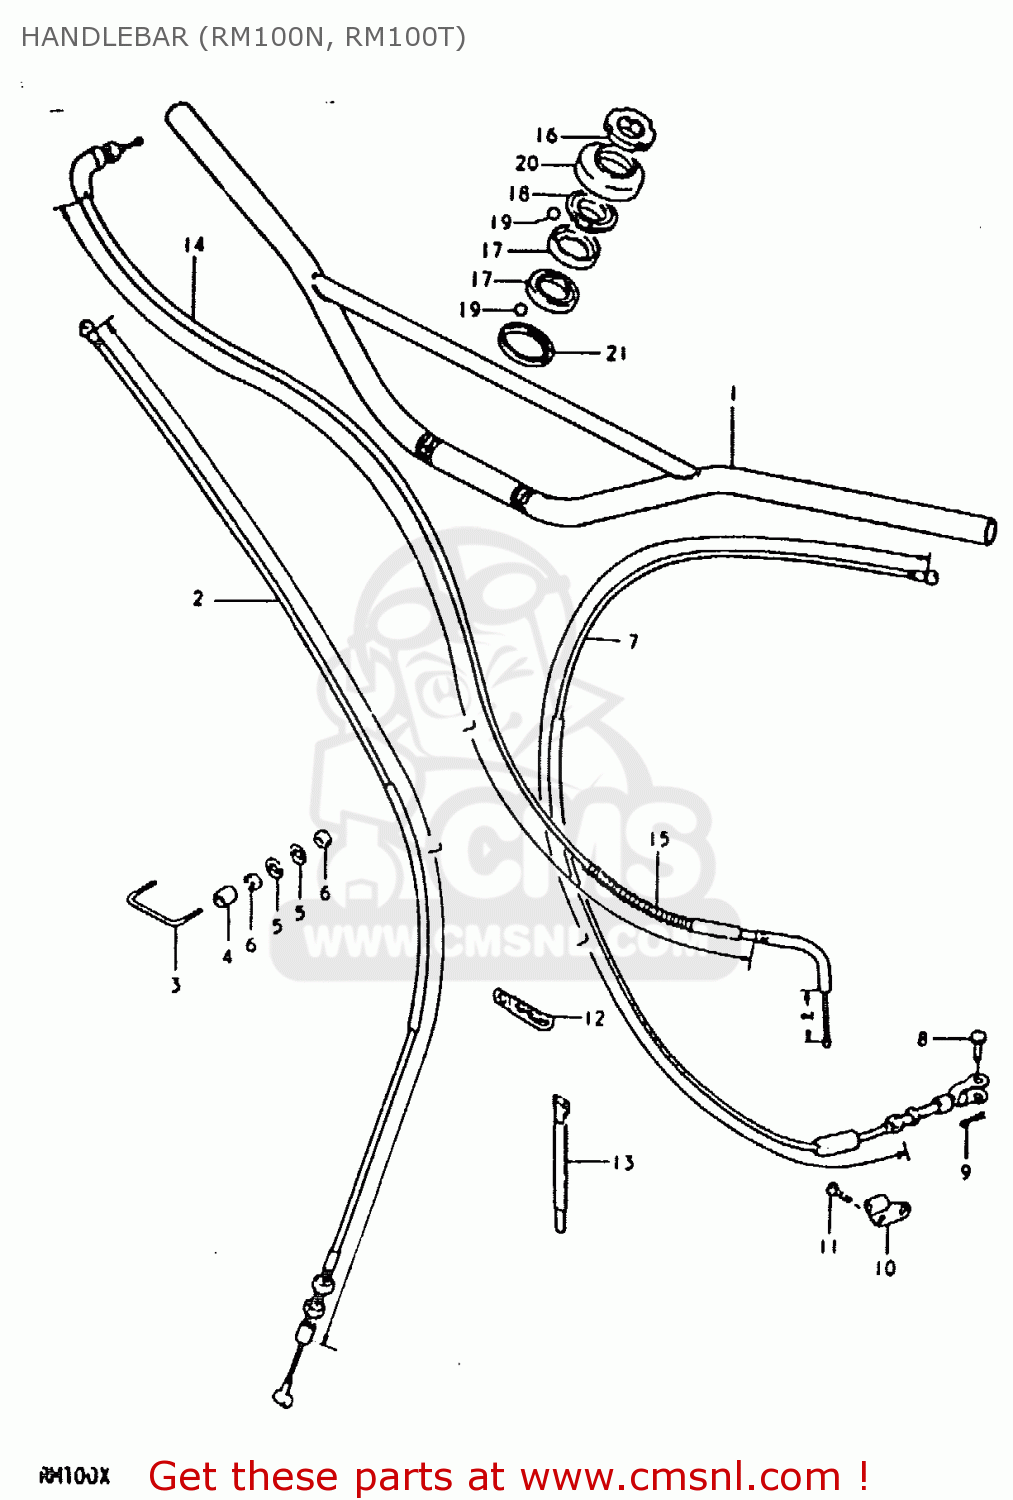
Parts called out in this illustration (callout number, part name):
1	HANDLEBAR
2	CABLE,FRONT BRAKE
3	CLAMP,CABLE
4	BUSHING
5	WASHER
6	NUT 3MM
7	CABLE ASSY,CLUTCH
8	PIN(L:13)
9	PIN
10	STOPPER,CLUTCH CABLE
11	SCREW
12	CLAMP L:35
13	CLAMP
14	CABLE ASSEMBLY,THROTTLE
15	PROTECTOR,CABLE
16	NUT,STEERING STEM
17	RACE,STEERING,INNER,UPPER
18	RACE,STEERING,OUTER,UPPER
19	BALL
20	SEAL,STEERING UPR DUST
21	DUST SEAL,STEERING HEAD
